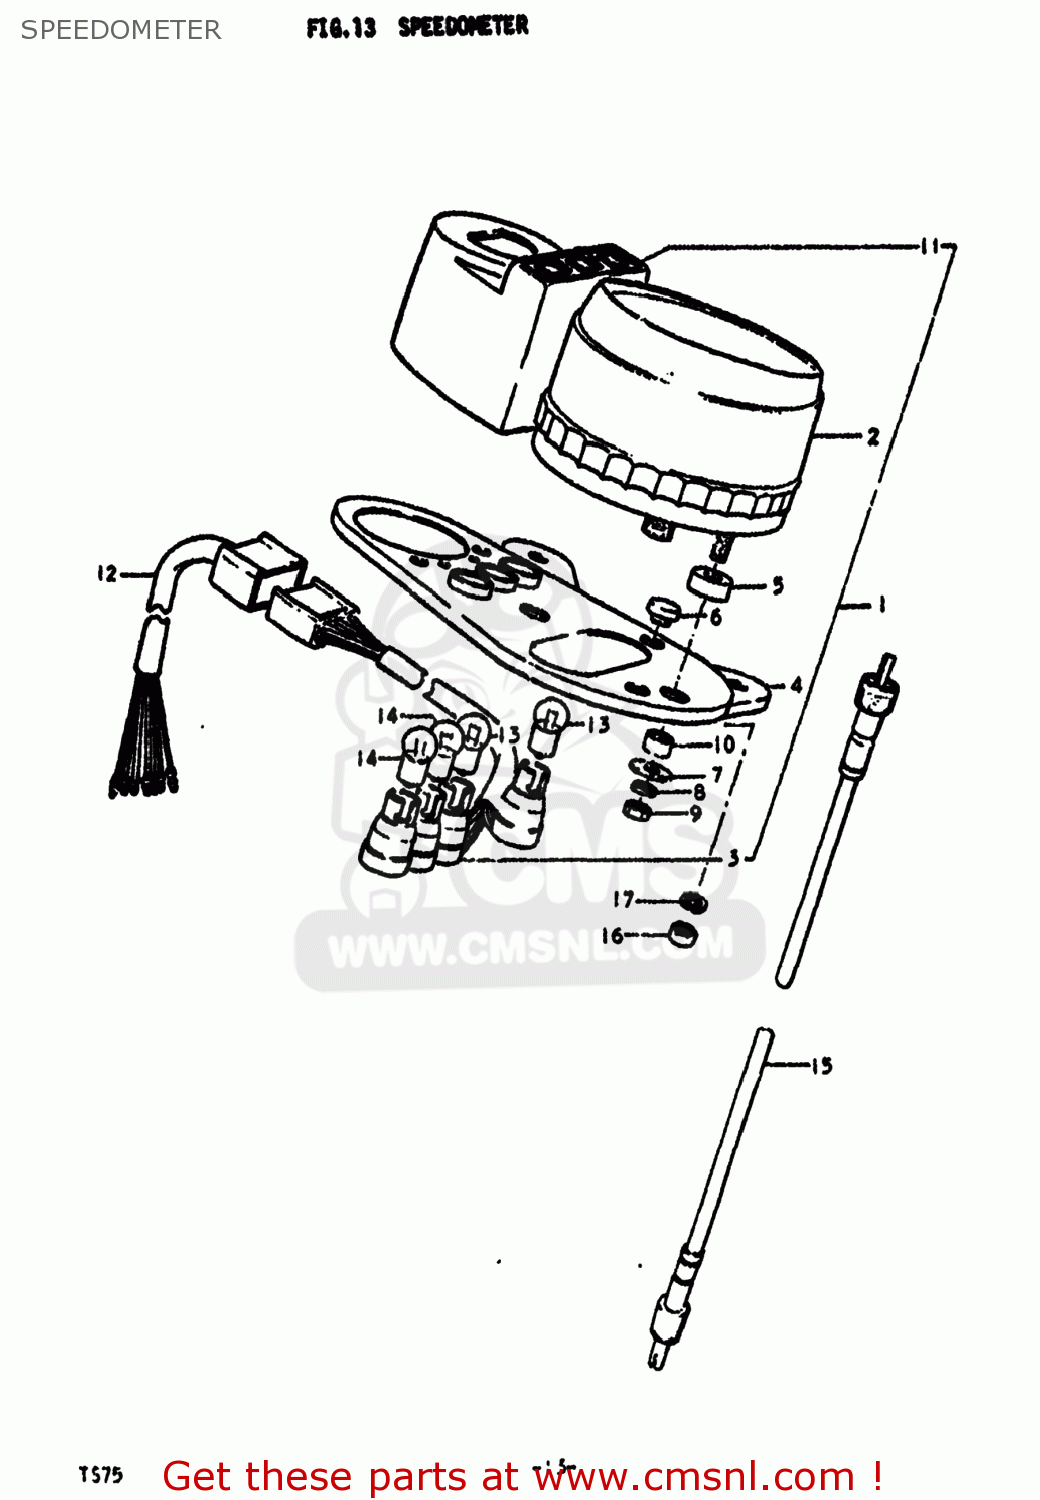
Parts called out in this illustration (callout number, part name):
1	SPEEDOMETER ASSEMBLY
2	SPEEDOMETER ASSEMBLY
3	SOCKET,METER
4	BRACKET,METER
5	CUSHION,METER NO.1
6	CUSHION,METER
7	WASHER
8	LOCK WASHER
9	NUT
10	SPACER,METER
11	CASE,PILOT BULB
12	LEAD WIRE
13	BULB(6V/3W)
14	BULB(6V1.7W,STANLEY,A61A)
15	CABLE ASSEMBLY,SPEEDOMETER
16	NUT
17	LOCK WASHER
